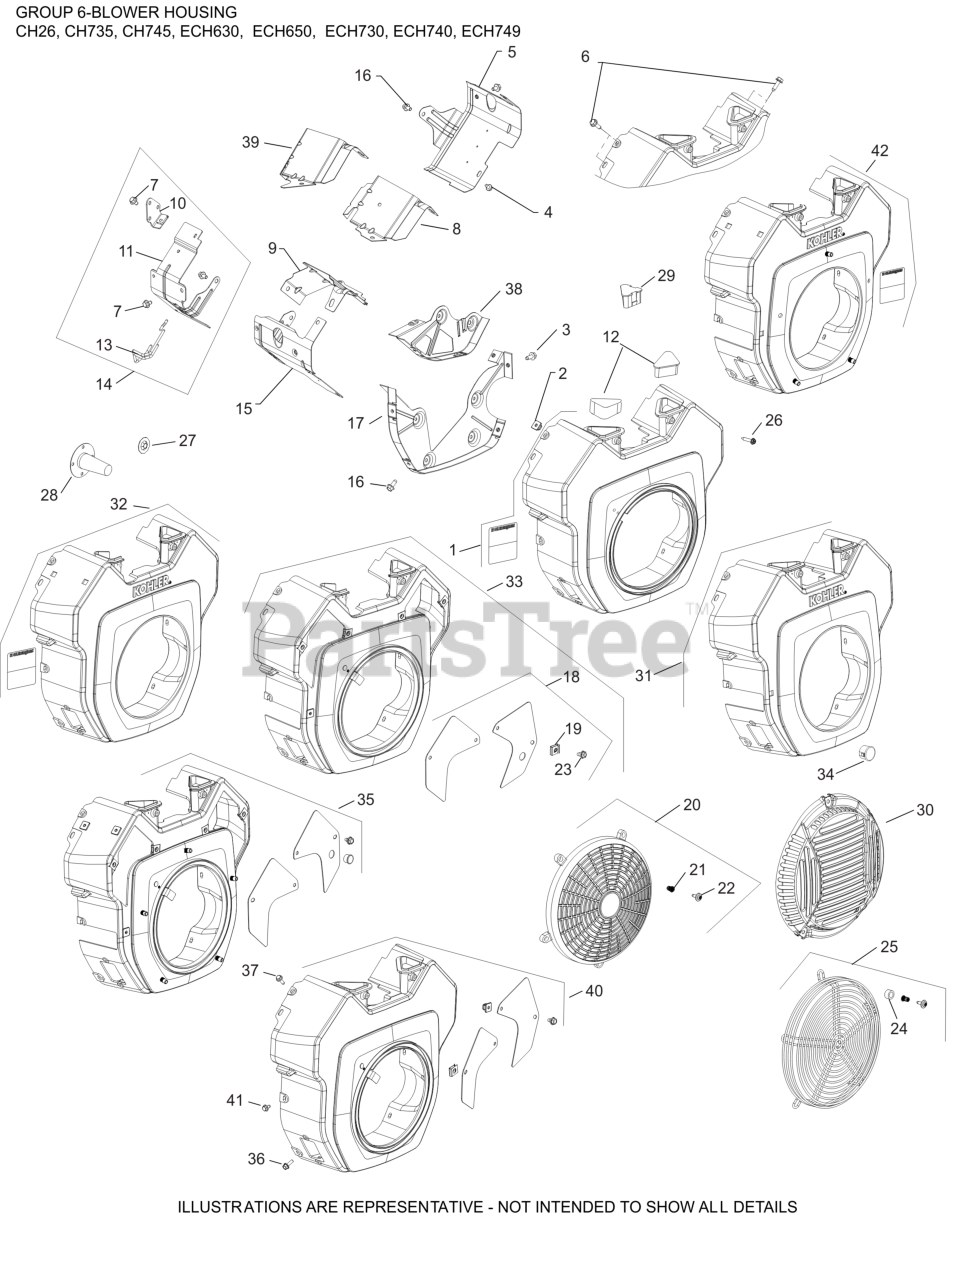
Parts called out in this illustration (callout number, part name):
1	KIT, BLOWER HOUSING
1	HOUSING, BLOWER
3	SCREW, THREAD FORMING
4	SCREW, THREAD FORMING
5	KIT, RIGHT BARREL
8	BAFFLE, VALLEY #1 CYLINDER
9	BAFFLE, VALLEY #2 CYLINDER
15	BAFFLE LEFT BARREL
16	SCREW, THREAD FORMING
17	PLATE, BACKING
17	KIT, BACKING PLATE
20	KIT, FIXED GUARD
21	INSERT, THREADED (M5)
22	SCREW, SEMS
29	COVER, BLOWER HOUSING
43	STRAP, LIFTING
